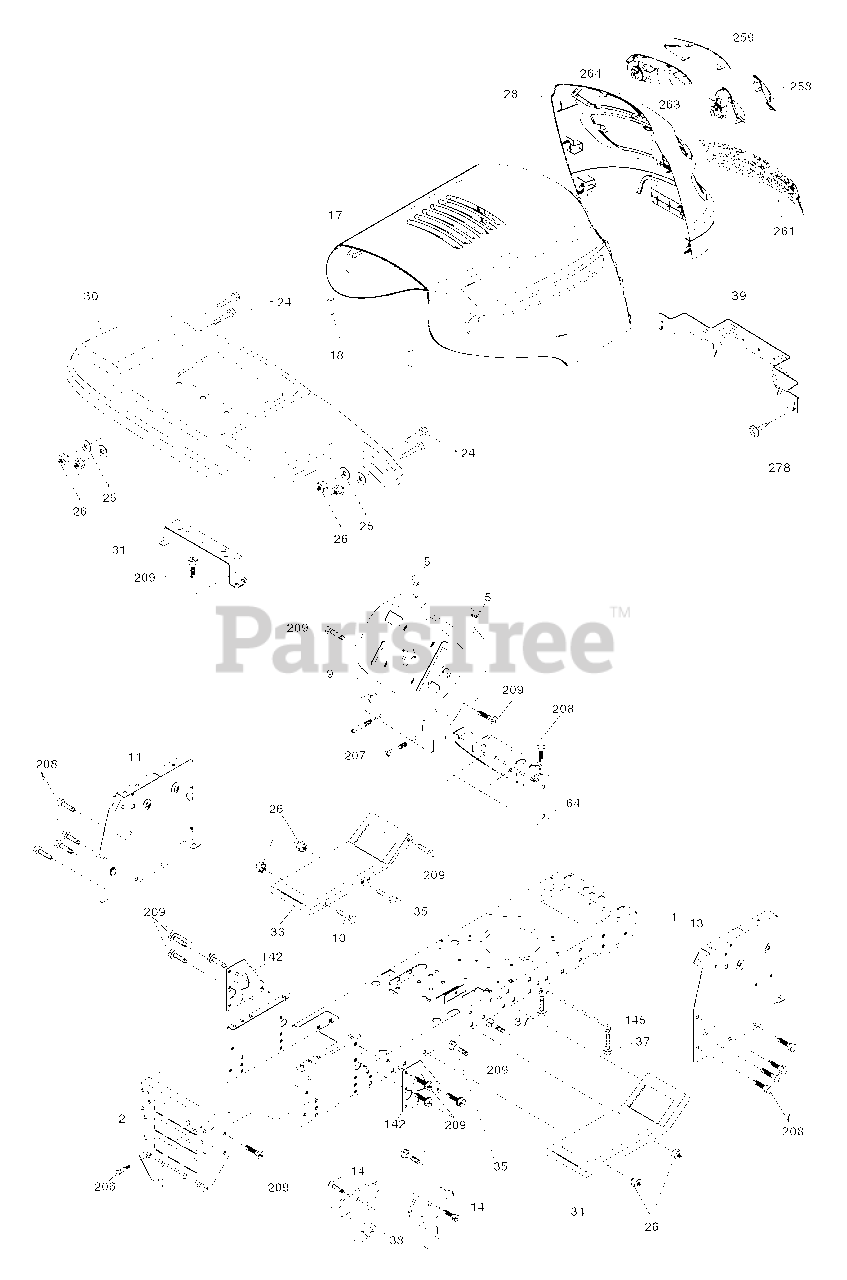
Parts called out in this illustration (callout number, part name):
1	Chassis
2	Drawbar
5	Bumper Hood/Dash
9	Dash
10	Bolt Carriage 3/8-16 x 1
11	Panel Dash Lh
14	Screw Thdrol 3/8-16 x 1-1/4
17	Hood
18	Bumper Hood
24	Bolt Fin Hex 3/8-16 x 1 Gr. 5
25	Washer 13/32 x 13/16 x 12 Ga.
26	Nut Lock Hex W/Ins 3/8-16 unc
28	Grille Asm
30	Fender Footrest STLT Pnt
31	Bracket Support Fender
33	Footrest Pnt Lh
34	Footrest Pnt Rh
35	Bolt Rdhd Sht Sqnk 3/8-16 x 3/4
37	Screw Thdrol 6/16-18 x 1/2 TYT
38	Bracket Asm. Pivot Mower Rear
39	Bracket Pivot
64	Dash Lower STLT
142	Plate Reinforcement STLT
145	Rod Pivot Chassis/Hood
206	Bolt Shoulder 5/16-18
207	Screw Thdrol 5/16-18 x 1/2
208	Screw Thdrol 3/8-16 x 1/2
209	Screw Hex Wsh Thdr. 3/8-16 x 3/4
258	Lens RH
259	Lens LH
263	Bezel RH
264	Bezel LH
278	Screw 10 x 3/4 Single Lead-Hex
